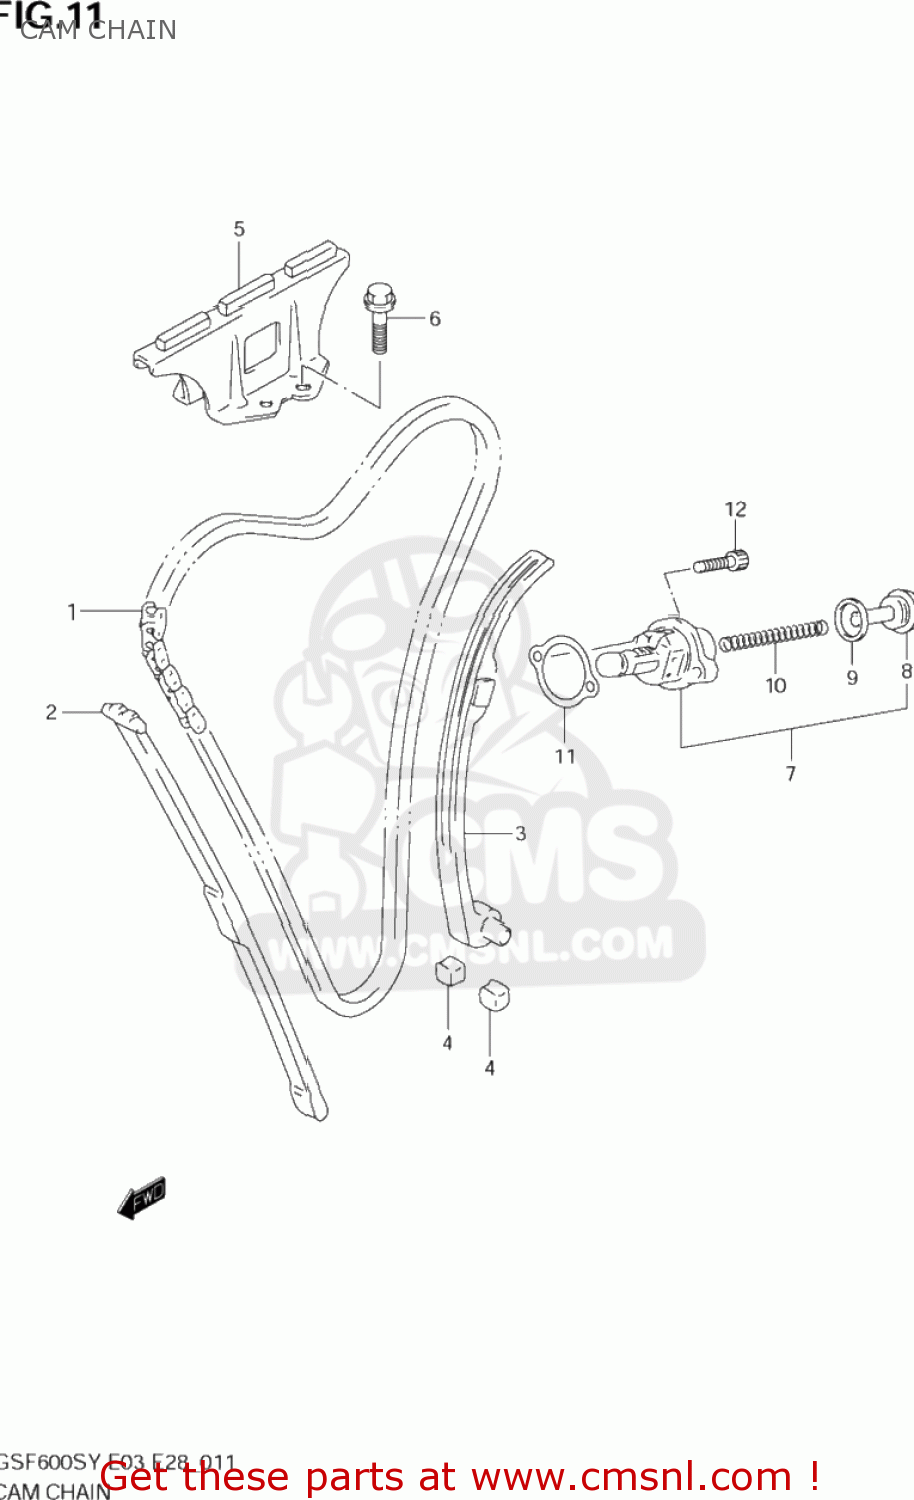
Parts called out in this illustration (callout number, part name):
1	CHAIN,CAMSHAFT DRIVE
2	GUIDE,CAM CHAIN NO.1
3	TENSIONER,CAM CHAIN
4	CUSHION,CAM CHAIN TENSIONER
5	GUIDE,CAM CHAIN NO.2
6	BOLT
7	ADJUSTER ASSY,TENSIONER
8	PLUG
9	GASKET (NAS)
10	SPRING
11	GASKET,TENSIONER ADJUSTER (NAS)
12	BOLT,CL.COVER
